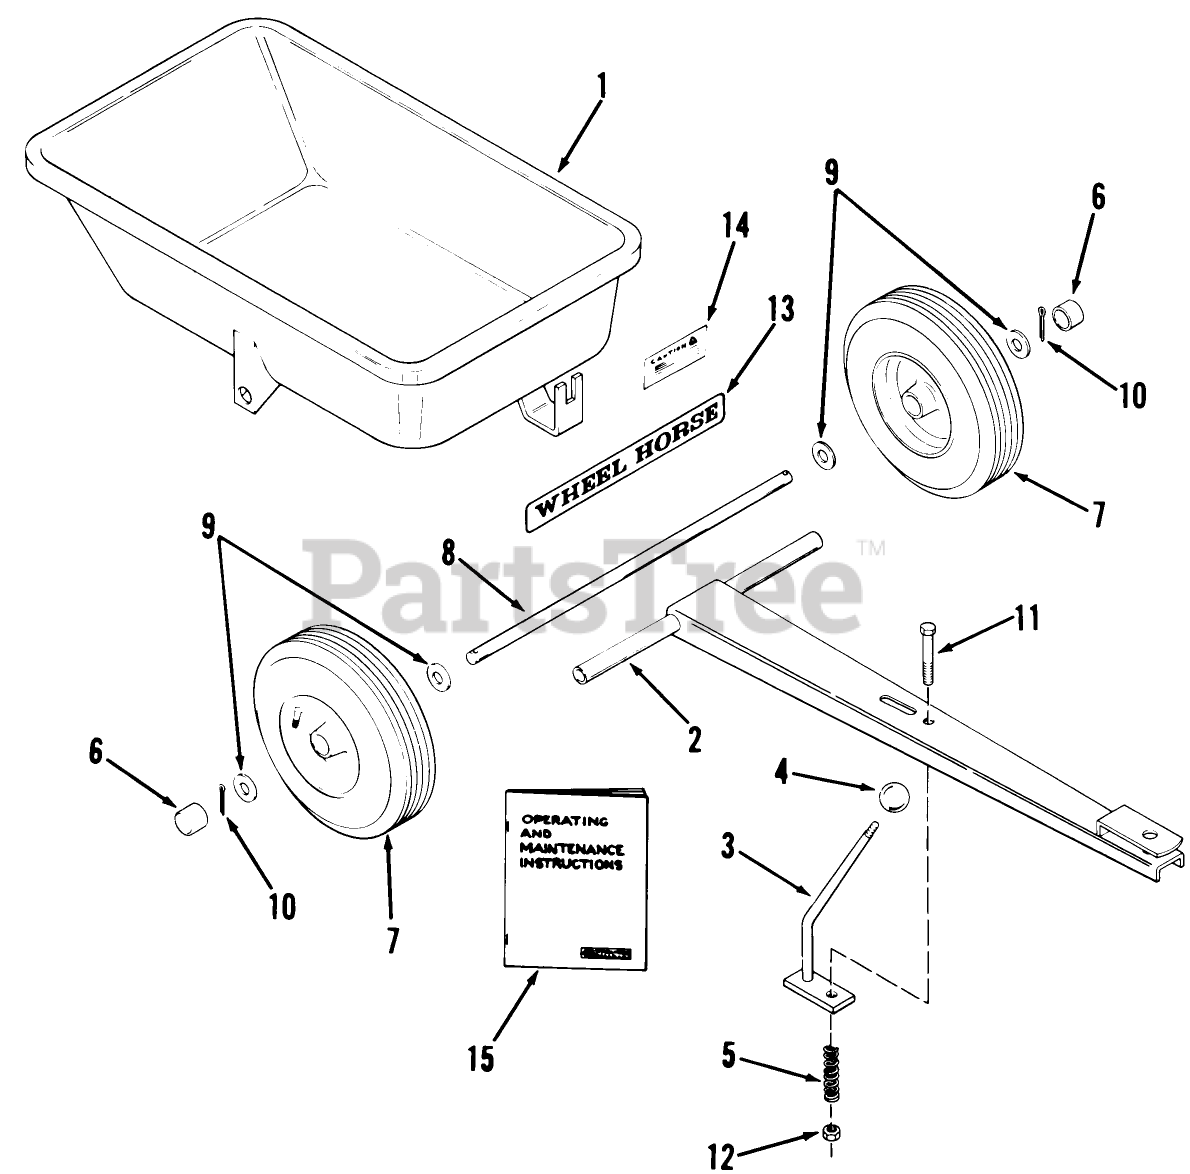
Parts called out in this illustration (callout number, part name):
1	Box Ass-y.
9	WASHER
15	MANUAL-OPERATOR
